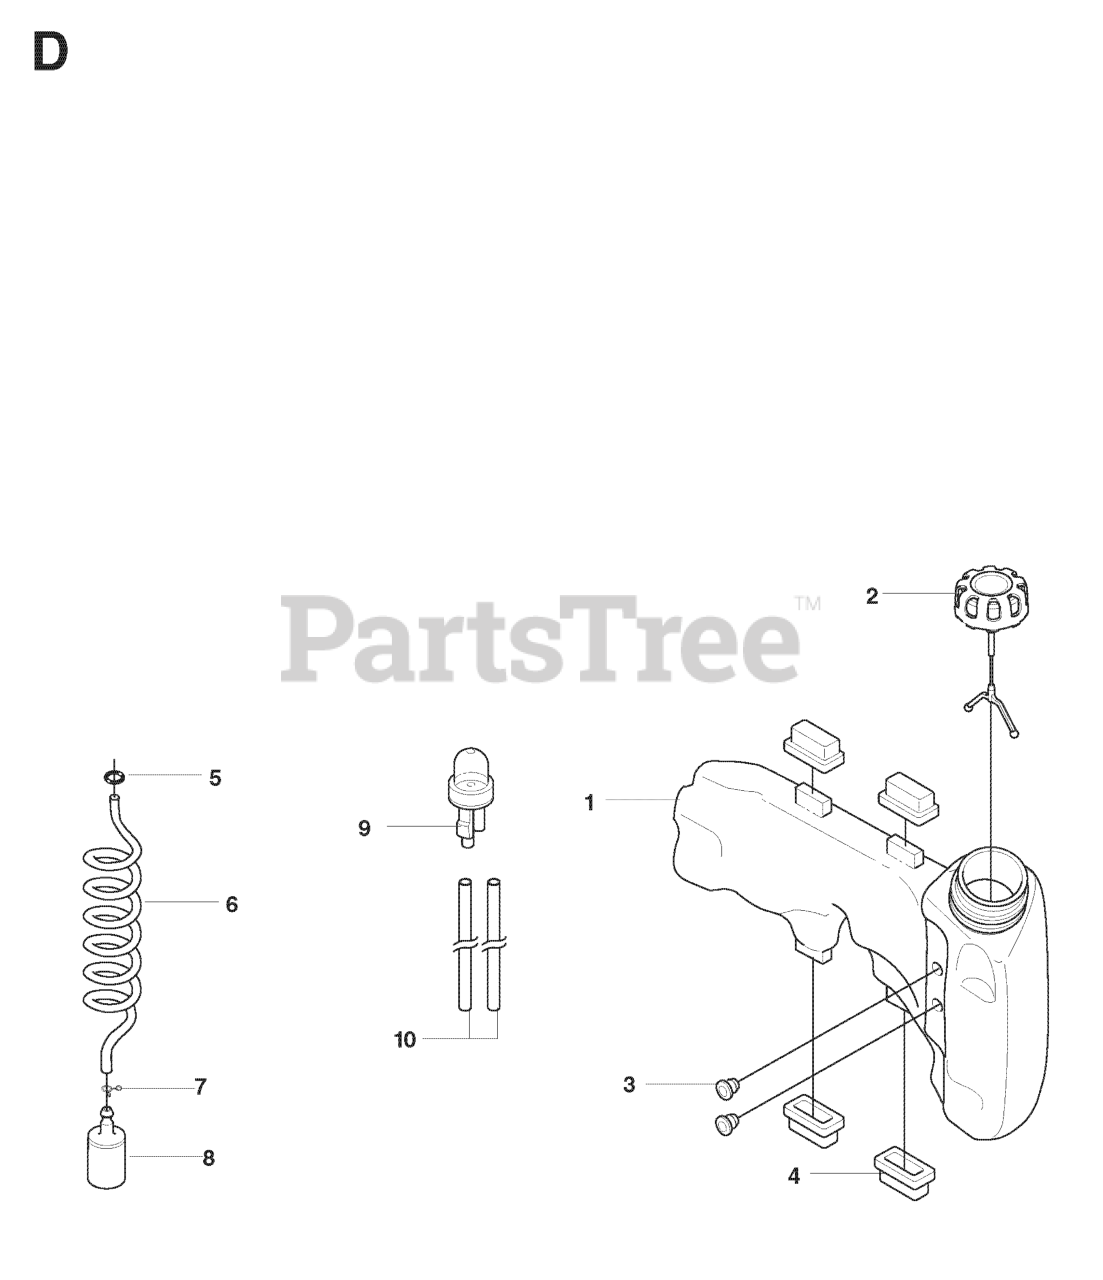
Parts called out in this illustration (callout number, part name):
3	FUEL TANK BUSHING
6	FUEL HOSE
8	RP FUEL FILTER
9	AIR PURGE BUBBLE
10	HOSE
